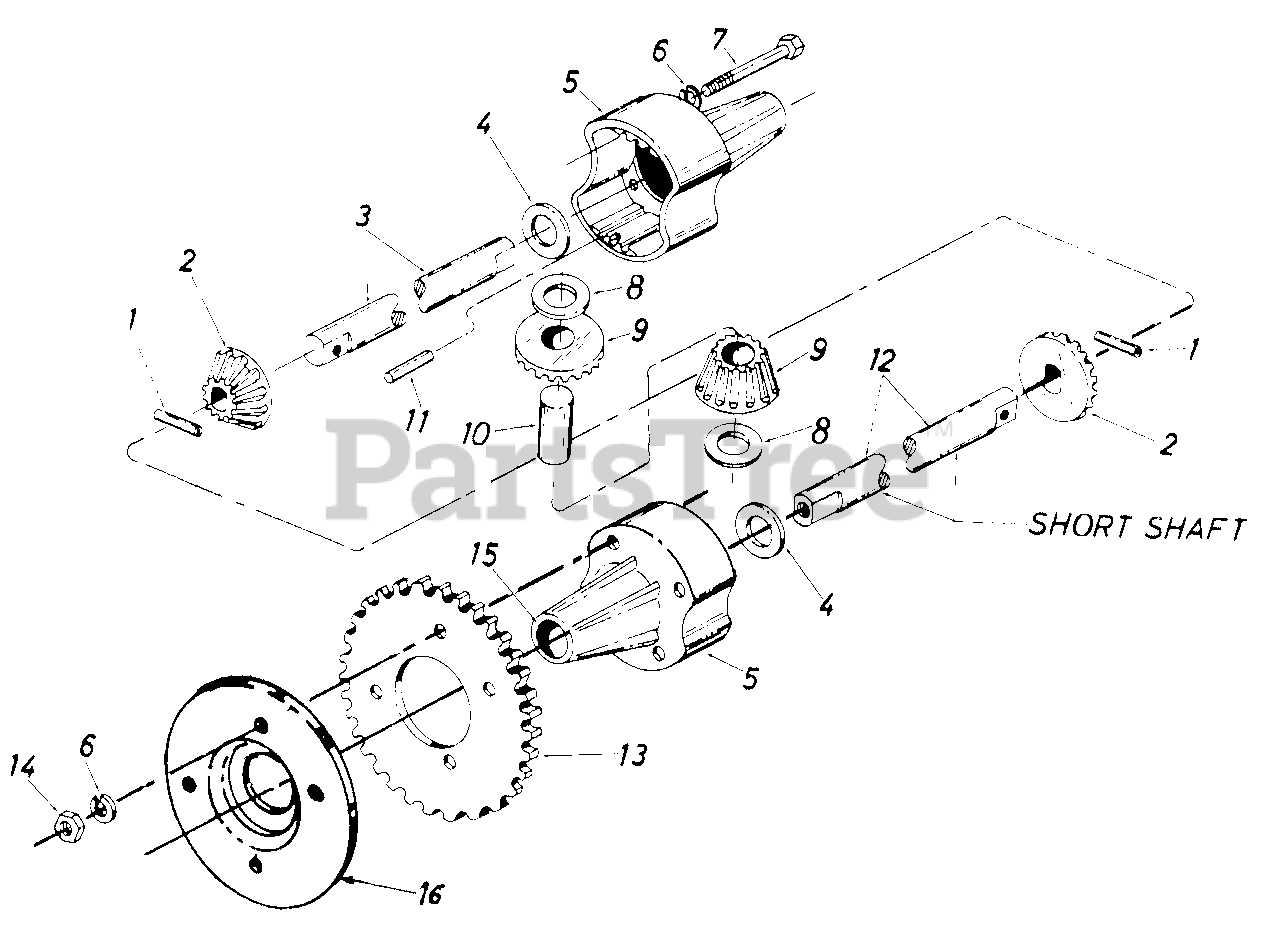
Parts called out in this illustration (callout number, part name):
1	Spring Pin Spiral 3/16" Dia. x 1.00" Lg.
2	Gear - Double "D" Hole
3	Shaft - Long - 19.81" Lg.
4	Fl-Wash. .760 I.D. x 1.49 O.D.
5	Housing Half
6	L-Wash. 5/16" I.D.
7	Hex Bolt 5/16-24 x 4.00" Lg.
8	Fl-Wash. .640 I.D. x .24 O.D.
9	Gear - Round Hole
10	Drive Pin
11	Dowel Pin 3/16" Dia. x .62" Lg.
12	Shaft - Short - 8.52" Lg.
13	Sprocket - 48 Teeth
14	Hex Cent. L-Nut 5/16-24 Thd.
15	Flange Bearing
16	Brake Disc
